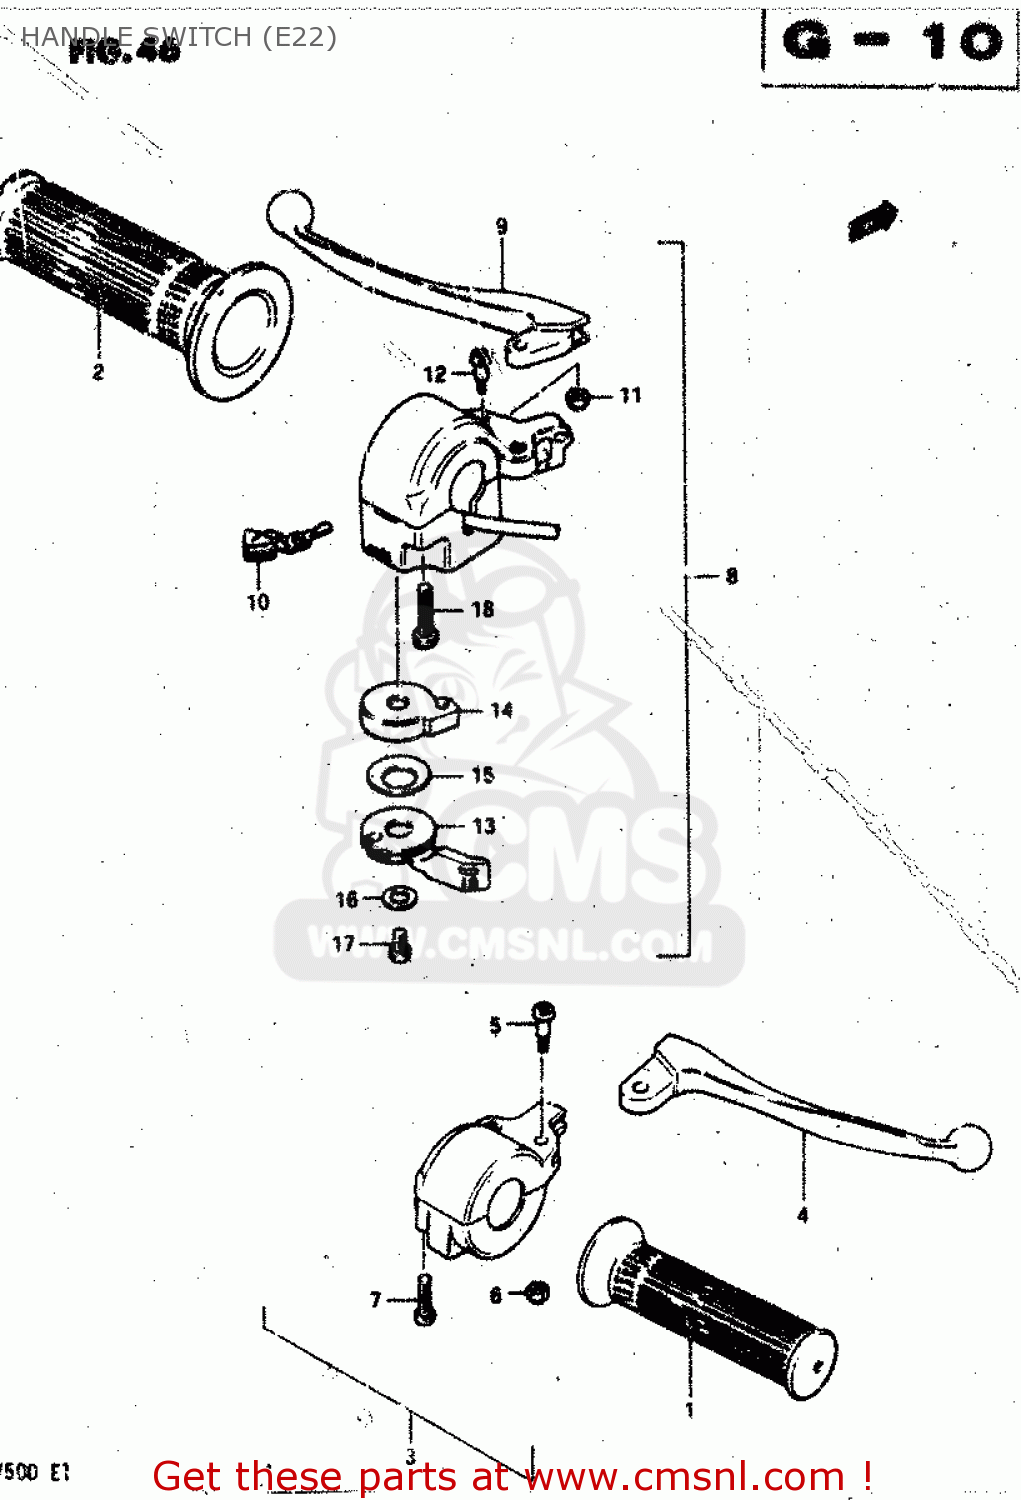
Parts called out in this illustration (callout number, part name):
1	GRIP,THROTTLE
2	GRIP,L
3	BRAKE LEVER & SWITCH ASSY
4	LEVER
5	BOLT,LEVER
6	NUT,LEVER BOLT
7	SCREW
8	CLUTCH LEVER & SWITCH ASSY
9	LEVER
10	KNOB,TURN SIGNAL SWITCH
11	NUT,LEVER BOLT
12	BOLT,LEVER
13	LEVER,STARTER
14	BODY,STARTER LEVER
15	WASHER,ADJUSTER
16	WASHER
17	SCREW
18	SCREW 5X20
